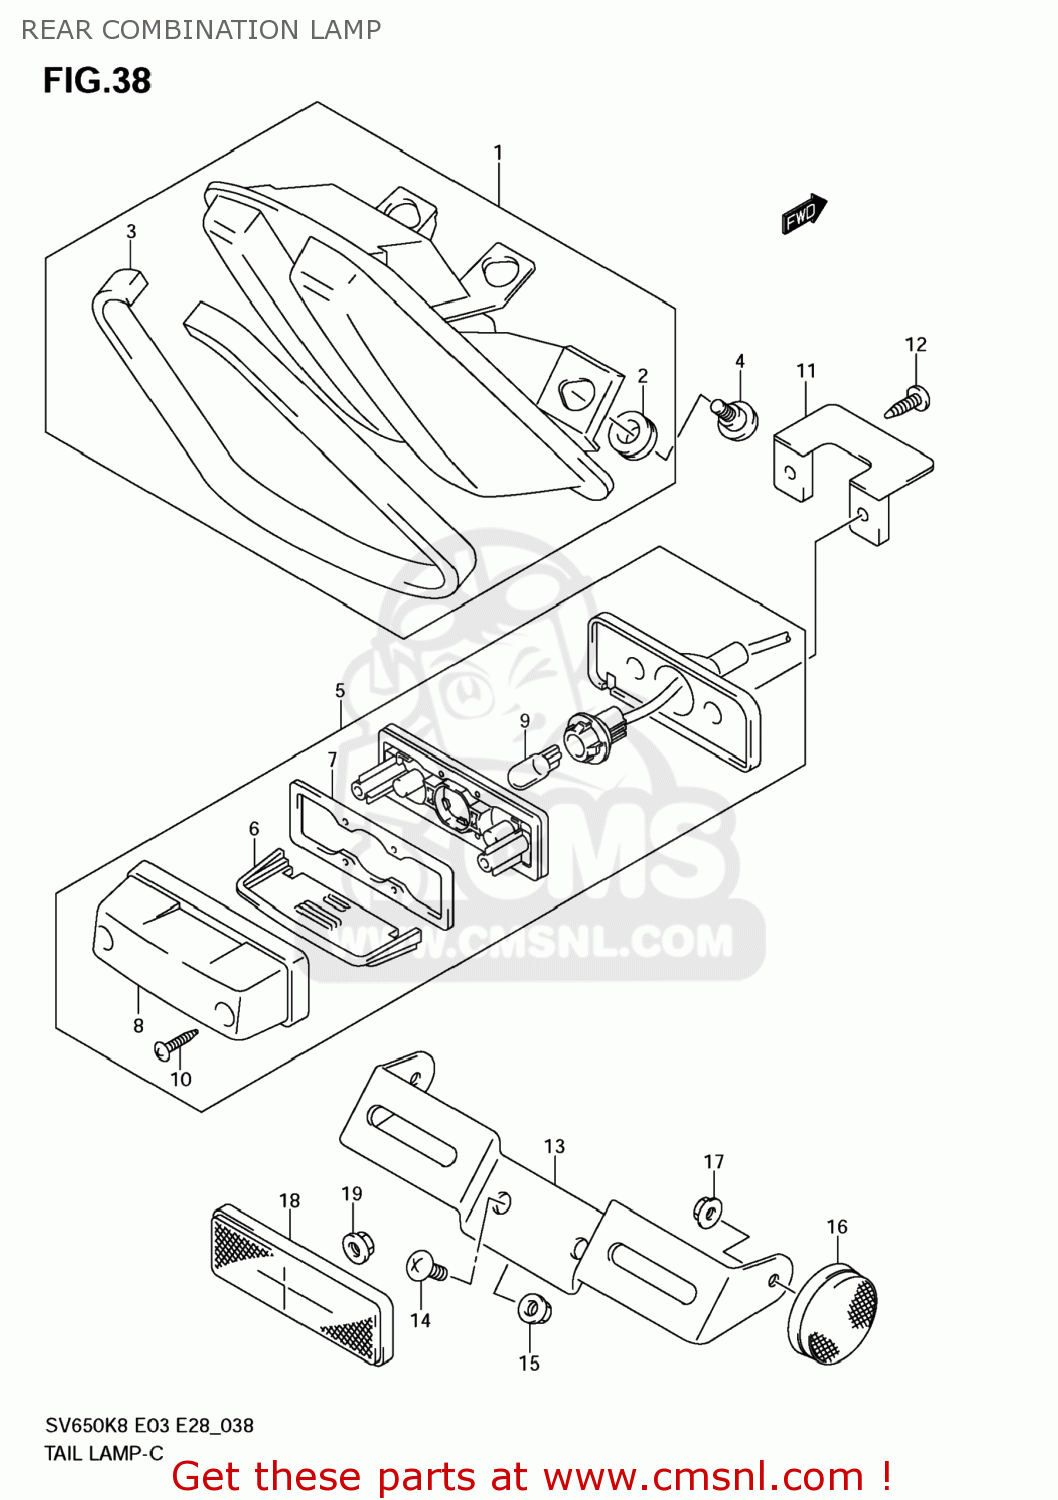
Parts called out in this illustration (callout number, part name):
1	LAMP ASSY,RR COMBINATION
2	CUSHION
3	CUSHION,SEAT TAIL COVER
4	SCREW(6X22.5)
5	LAMP ASSY,LICENSE
6	LENS
7	GASKET (NAS)
8	COVER
9	BULB(12V5W)
10	SCREW
11	BRACKET,LICENSE
12	SCREW
13	BRACKET,LICENSE PLATE
14	SCREW
15	NUT
16	REFLECTOR ASSY,RR SIDE
17	NUT
18	REFLECTOR ASSY,RR
19	NUT
